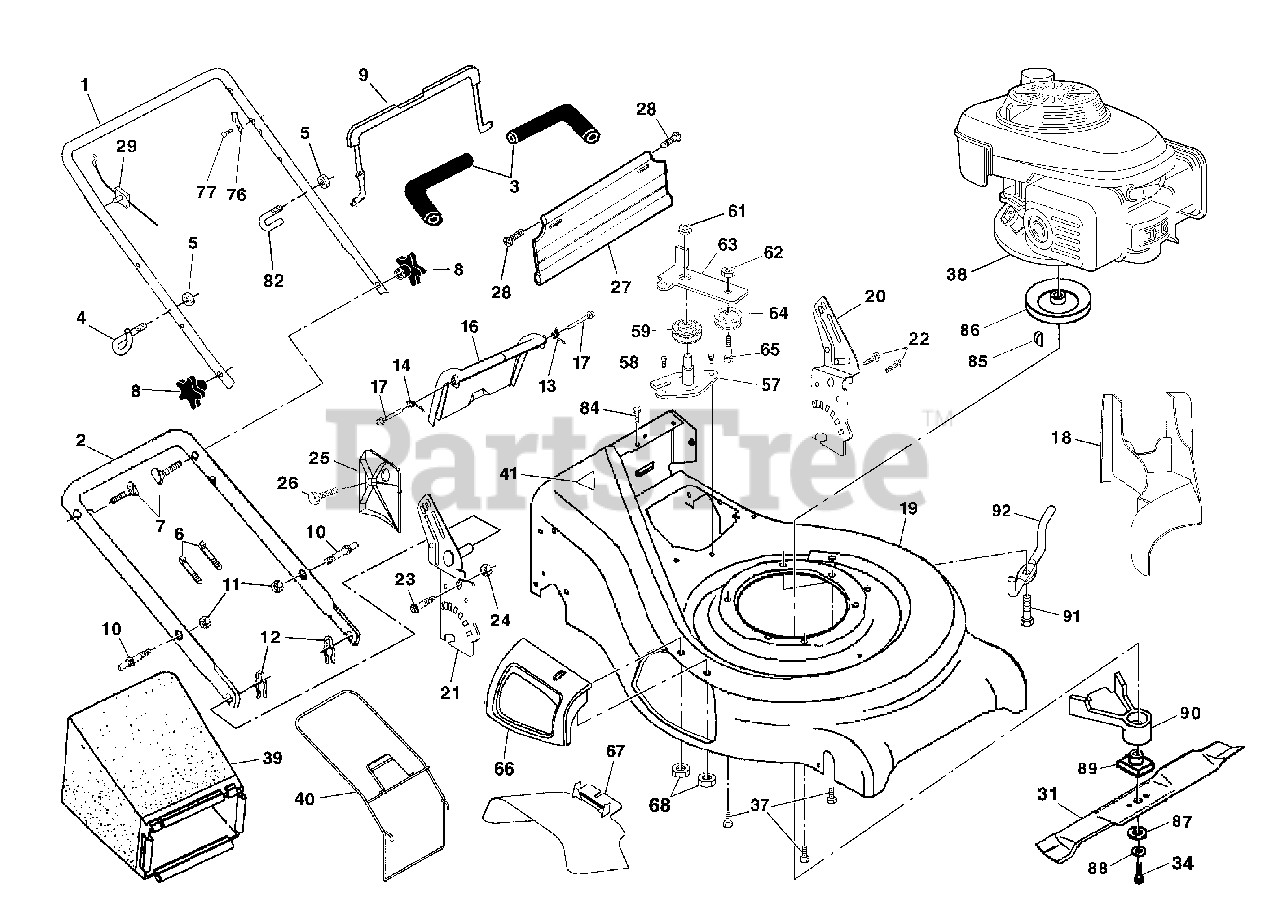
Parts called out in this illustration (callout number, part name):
1	Handle, Upper
2	Handle, Lower
3	Grip, Handle, Foam, Smooth
4	Guide, Rope, Side
5	Nut, Hex Lockwasher Insert 1/4-20
6	Wire, Tie
7	Bolt, Handle 5/16-18 x 1.75
8	Knob, Handle
9	Bail, Flat, Auto-Walk, Orange
10	Bolt, Carriage
11	Nut, Hex, Centerlock 5/16-18 UNC
12	Cotter, Hairpin
13	Spring, Rear Door, LH
14	Spring, Rear Door, RH
16	Rear Door Assembly
17	Bolt, Rear Door
18	Plug, Mulcher
19	Kit, Housing
20	Handle Bracket Assembly, LH
21	Handle Bracket Assembly, RH
22	Screw, Hex Washer Head
23	Bolt, Hex Head 5/16-18 x 5/8
24	Nut, Hex, with Lock Washer Insert 5/16-18
25	Baffle, Side
26	Screw 12 x 5/8
27	Skirt, Rear
28	Screw, Hinge 1/4-20 x 1.25
29	Engine Zone Control Cable
31	Blade, 21"
34	Screw, Hex Head 3/8-24 x 1.38
37	Bolt, Engine
40	Frame, Grassbag
41	Danger Decal
57	Bracket Assembly
59	Pulley Assembly, V-Groove
61	Flange Nut
62	Locknut
63	Idler Arm
64	Idler Pulley
65	Shoulder Bolt
66	Mulcher Door Assembly
67	Deflector, Discharge
76	Bracket, Upstop
85	Hi-Pro Key
86	Pulley, Engine
87	Washer, Hardened
88	Lockwasher, Helical Spring 3/8
89	Adapter, Blade
90	Debris Shield
91	Screw
92	Mounting Bracket, Debris Shield
